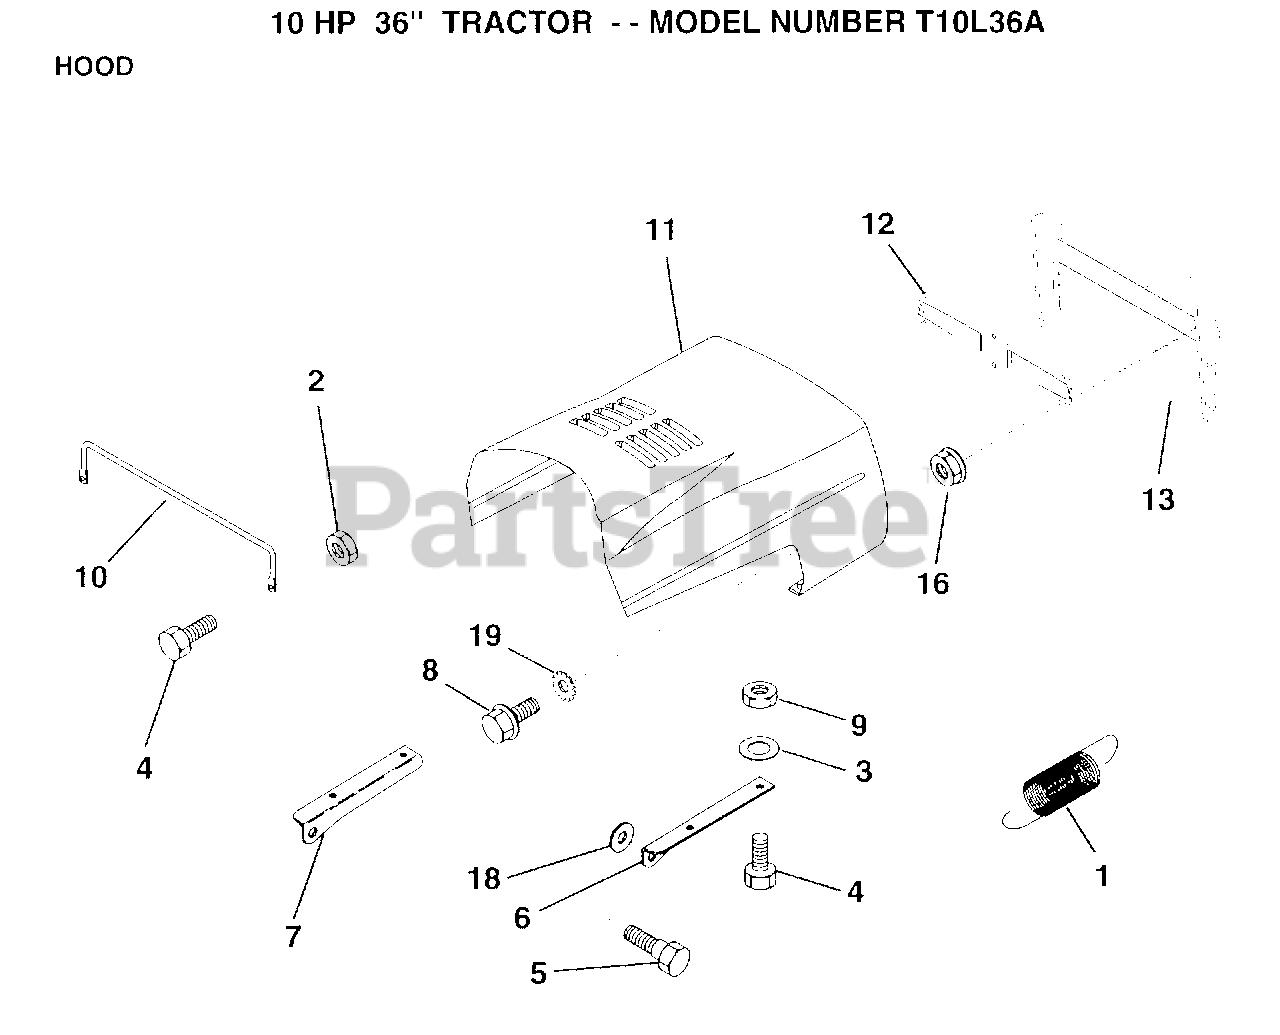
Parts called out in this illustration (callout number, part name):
1	EXT SPRING
2	NUT
3	WASHER
6	BRKT HOOD RH
7	BRKT HOOD LH
8	SCREW SLTD HXHD
9	NUT
10	"BRACE,HOOD"
11	HOOD
16	NUT
18	WASHER
19	LOCKWASHER GT
